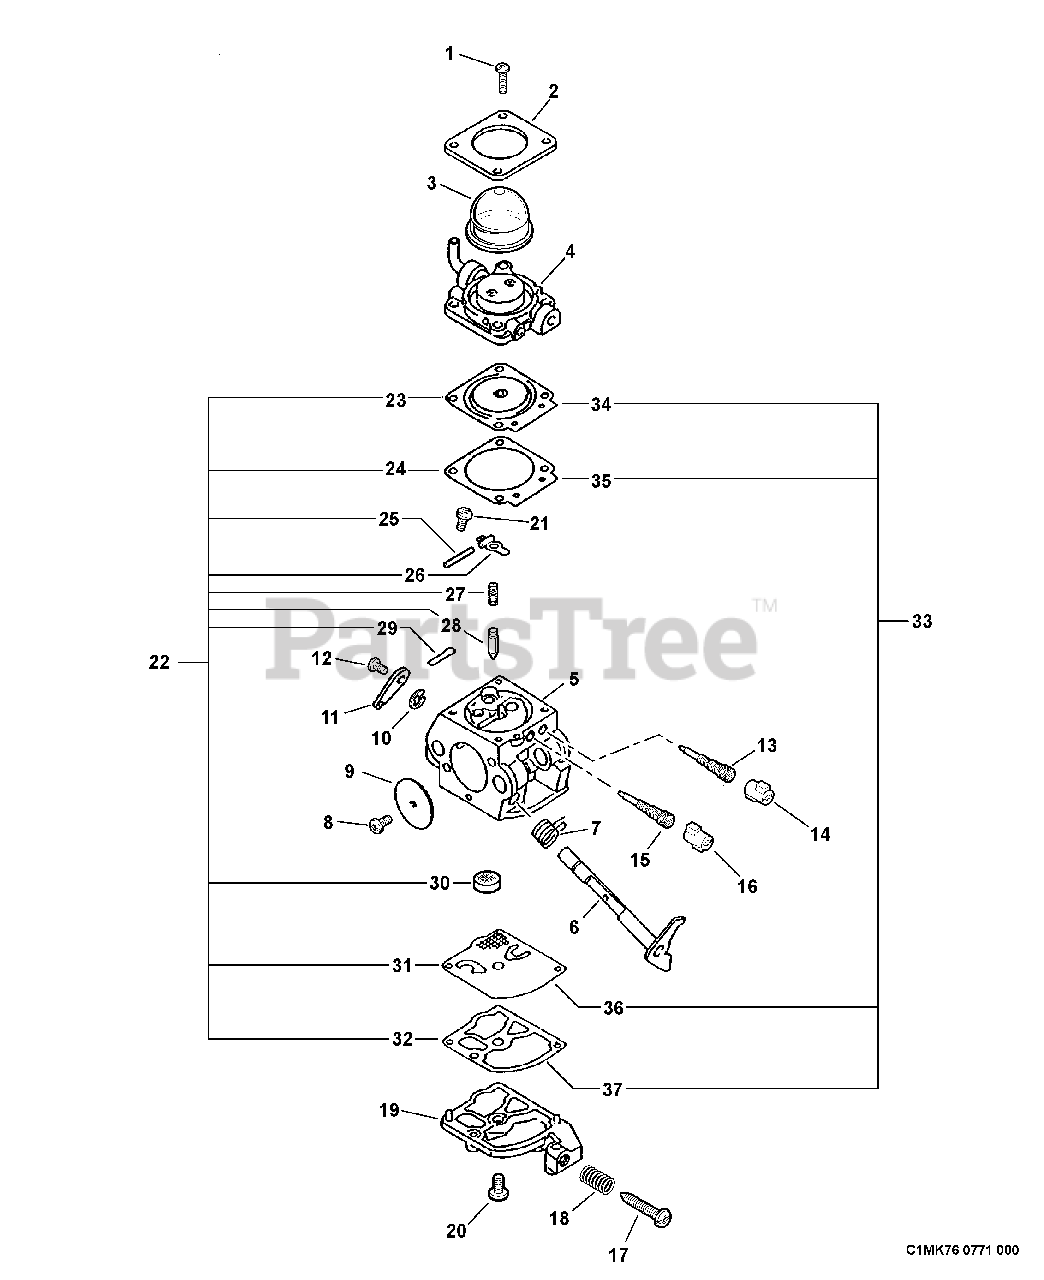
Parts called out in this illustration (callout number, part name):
1	SCREW, RETAINER
2	RETAINER, PURGE BULB
3	BULB, PURGE
4	BASE, PURGE
5	BODY, CARBURETOR
6	SHAFT, THROTTLE
7	SPRING, TRIGGER
9	VALVE, THROTTLE
10	RING, RETAINING
11	LEVER, THROTTLE
13	NEEDLE - HIGH SPEED
14	CAP, LIMITER
15	NEEDLE - LOW SPEED
16	CAP, LIMITER
17	SCREW, IDLE ADJUST
18	SPRING, IDLE ADJUST
19	COVER, FUEL PUMP
20	SCREW, PUMP COVER
21	SCREW, METERING LEVER PIN
22	REPAIR KIT
23	DIAPHRAGM, METERING
24	GASKET, METERING
25	PIN, METERING LEVER
26	LEVER, METERING
27	SPRING, METERING LEVER
28	VALVE, INLET NEEDLE
29	PLUG, WELCH
30	STRAINER
31	DIAPHRAGM, PUMP
32	GASKET, PUMP
33	DIAPHRAGM/GASKET KIT
34	DIAPHRAGM, METERING
35	GASKET, METERING
36	DIAPHRAGM, PUMP
37	GASKET, PUMP
